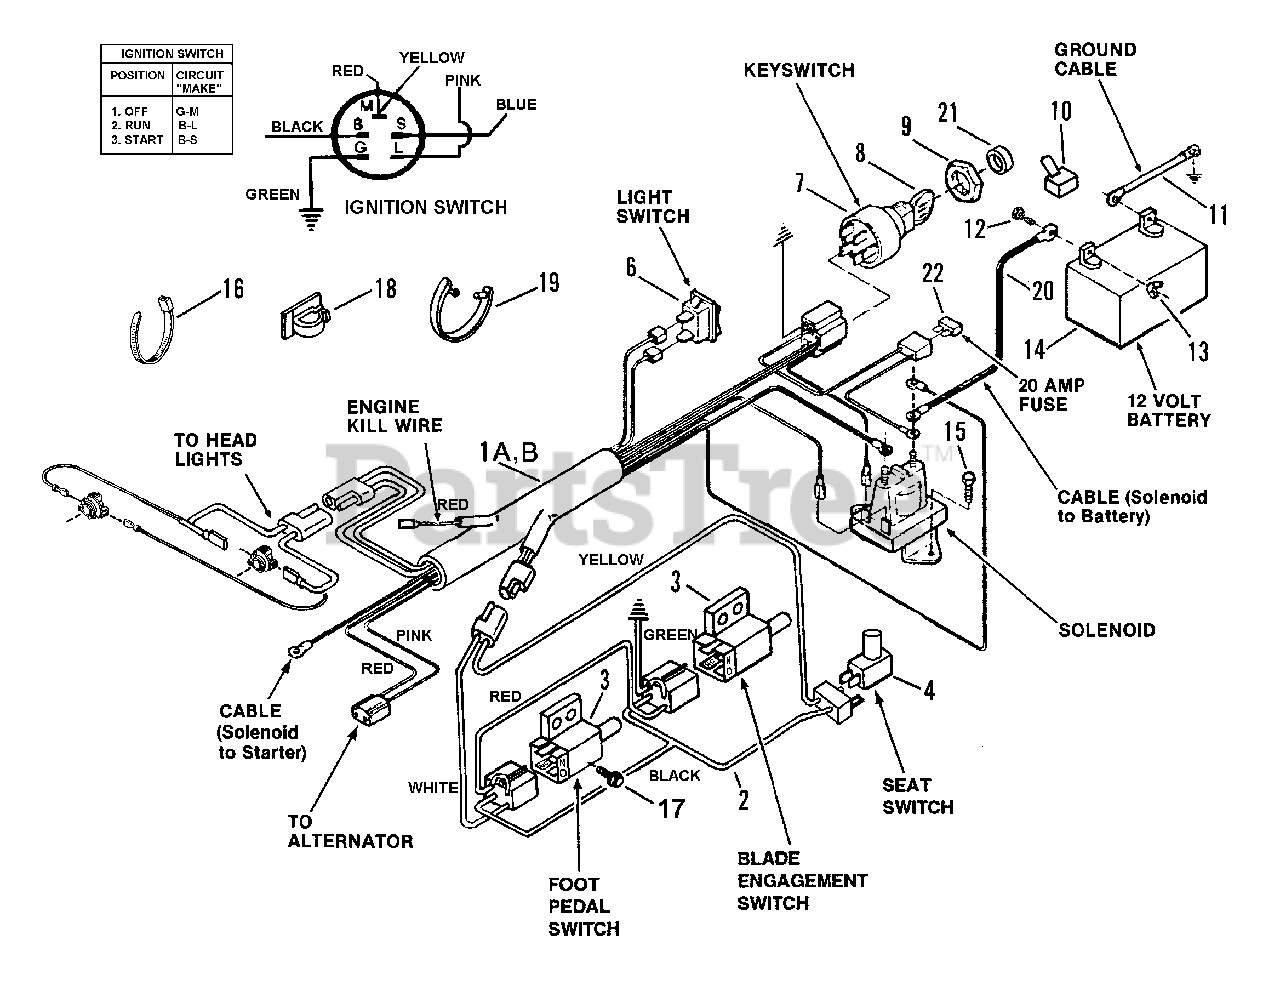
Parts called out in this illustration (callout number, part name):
1A	HARNESS, Wiring
1B	HARNESS, Wiring
2	HARNESS, Interlock
3	SWITCH, Clutch & PTO
4	SWITCH, Seat NC
6	SWITCH, Light
7	SWITCH, Key
8	KEY, Switch (With Cover)
9	NUT, 5/8-32 Hex
10	COVER, Positive Terminal
11	CABLE, Negative 15"
12	BOLT, 1/4-20 x 3/4" Carriage
13	WING NUT, 1/4-20
14	KIT, Battery
15	SCREW, 1/4-20 x 1/2" Self-Tapping
16	TIE, Wire
17	SCREW, #10-24 x 1/2" Hex Washer Self-Tap (Torx)
18	CLIP
19	TIE, Cable 7"
20	CABLE, Positive 11"
21	BEZEL
22	FUSE, 20 Amp
